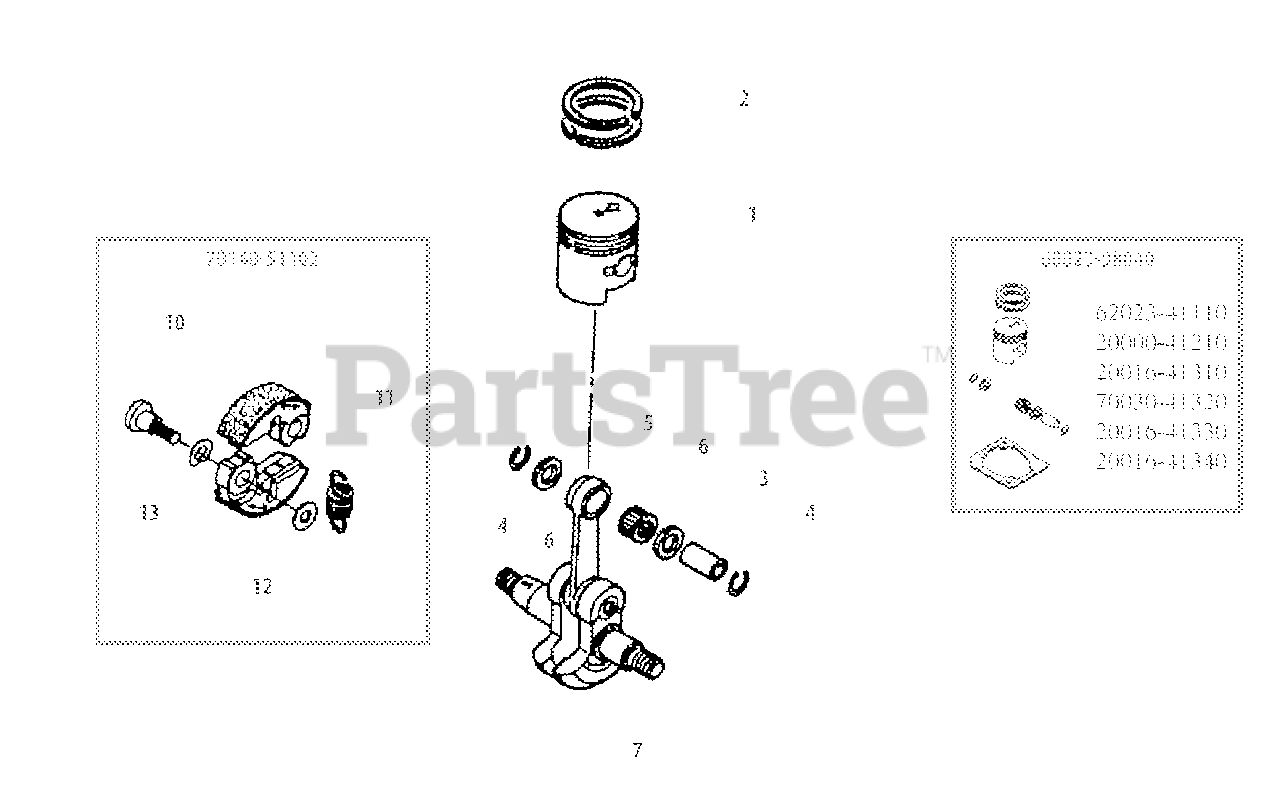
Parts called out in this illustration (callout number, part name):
1	PISTON
2	RING, PISTON
3	PIN, PISTON
4	RING, RETAINING
5	BEARING, NEEDLE
6	WASHER, THRUST
7	CRANKSHAFT ASSY
10	BOLT, CLUTCH
11	SPRING
12	WASHER - 6
13	WASHER - SPRING
60023-98040	PISTON ASSY
70140-51102	CLUTCH ASSY
